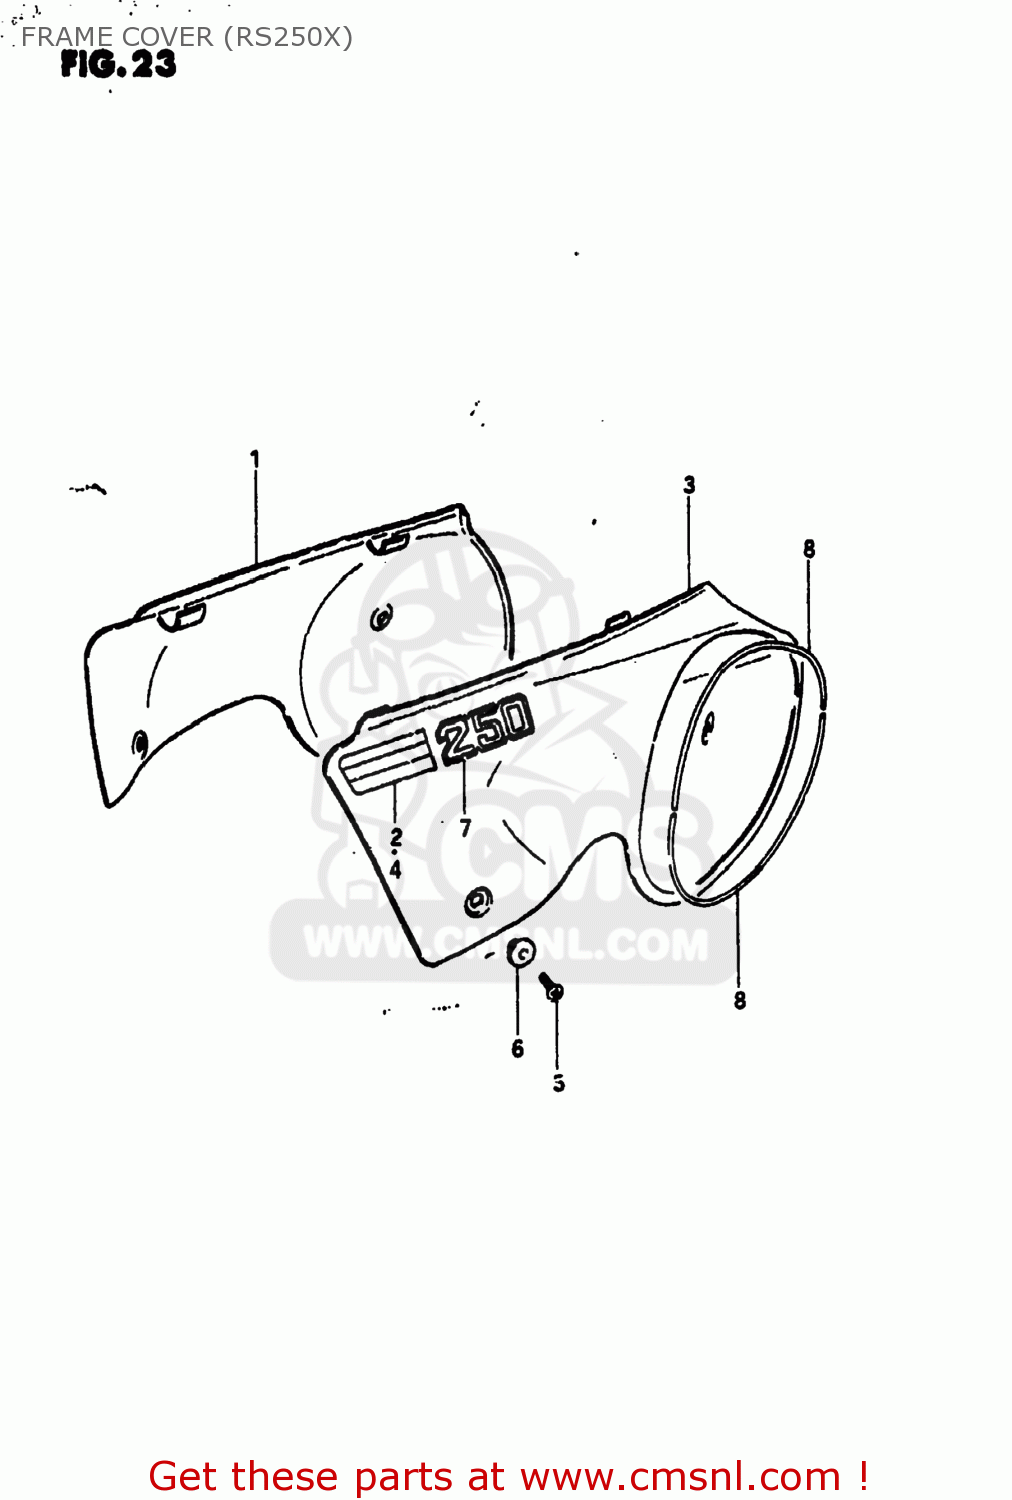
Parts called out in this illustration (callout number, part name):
1	COVER,FRAME,R(YELLOW)
2	TAPE,FRAME COVER,RIGHT
3	COVER,FRAME,L(YELLOW)
4	TAPE,FRAME COVER
5	SCREW
6	SPACER
7	EMBLEM (250)
8	TAPE,FRAME COVER
